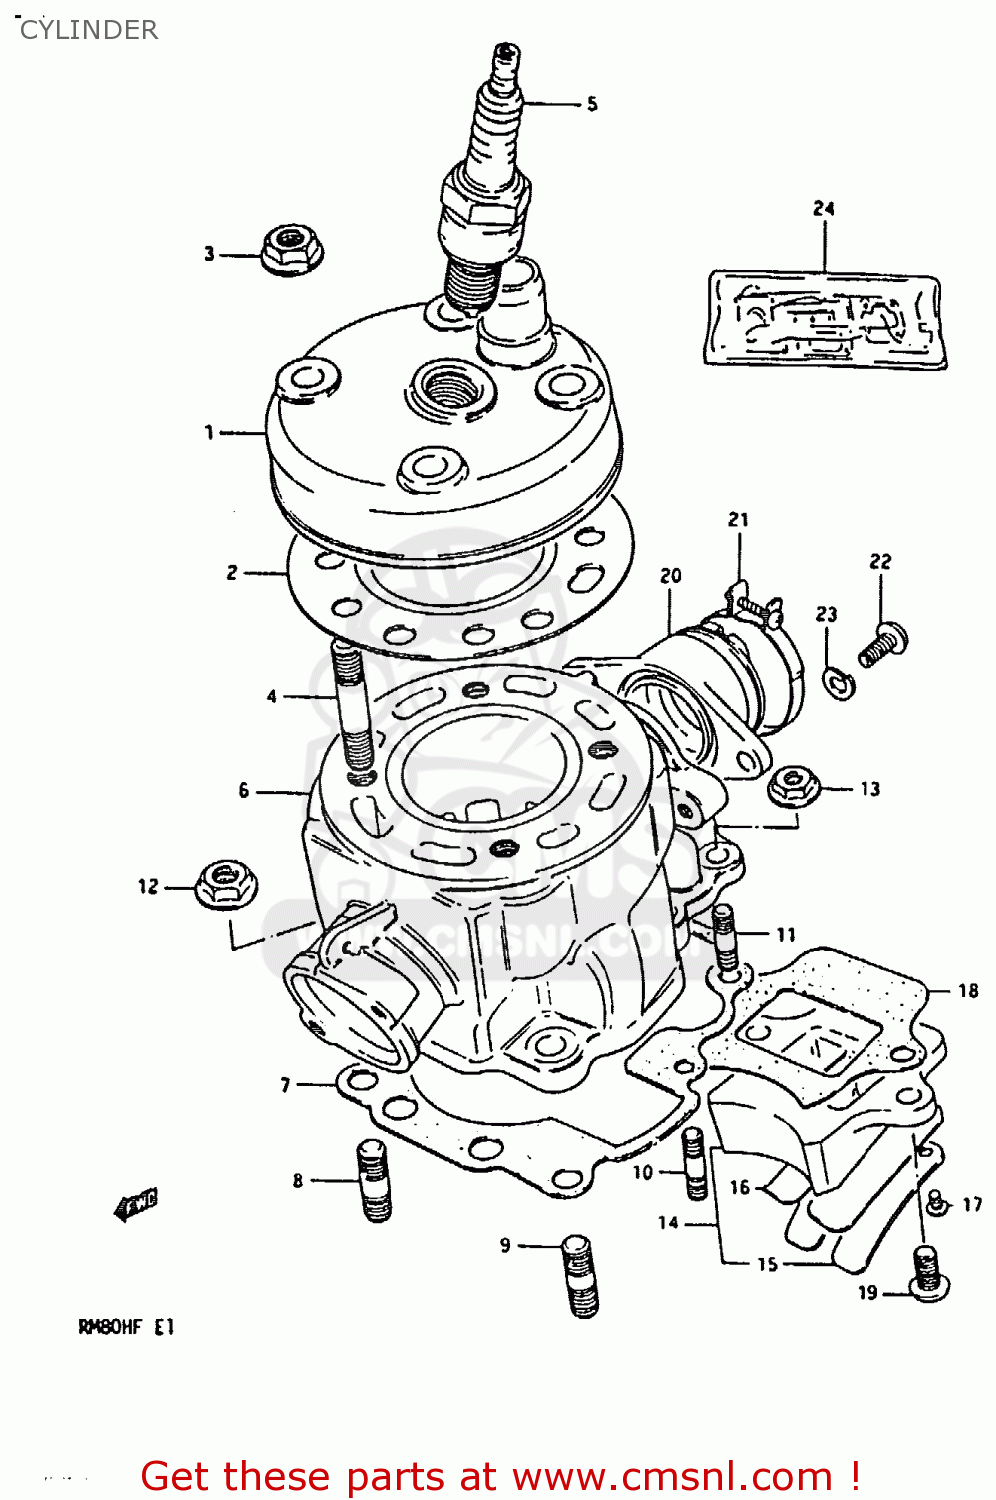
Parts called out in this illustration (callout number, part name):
1	HEAD,CYLINDER
2	GASKET,CYLINDER HEAD
3	NUT 8MM
4	BOLT,STUD
5	SPARK PLUG (NGK, BR9ES)
6	CYLINDER
7	GASKET,CYLINDER (MCA)
8	BOLT,STUD(8X20)
9	STUD BOLT
10	STUD BOLT L:20
11	STUD 6X16
12	NUT 8MM
13	NUT 6MM
14	VALVE ASSY,REED
15	STOPPER,REED VALVE
16	VALVE,REED
17	SCREW,REED VALVE
18	GASKET,REED VALVE (MCA)
19	SCREW
20	PIPE,INTAKE
21	CLAMP
22	BOLT
23	LOCK WASHER
24	GASKET SET (MCA)
